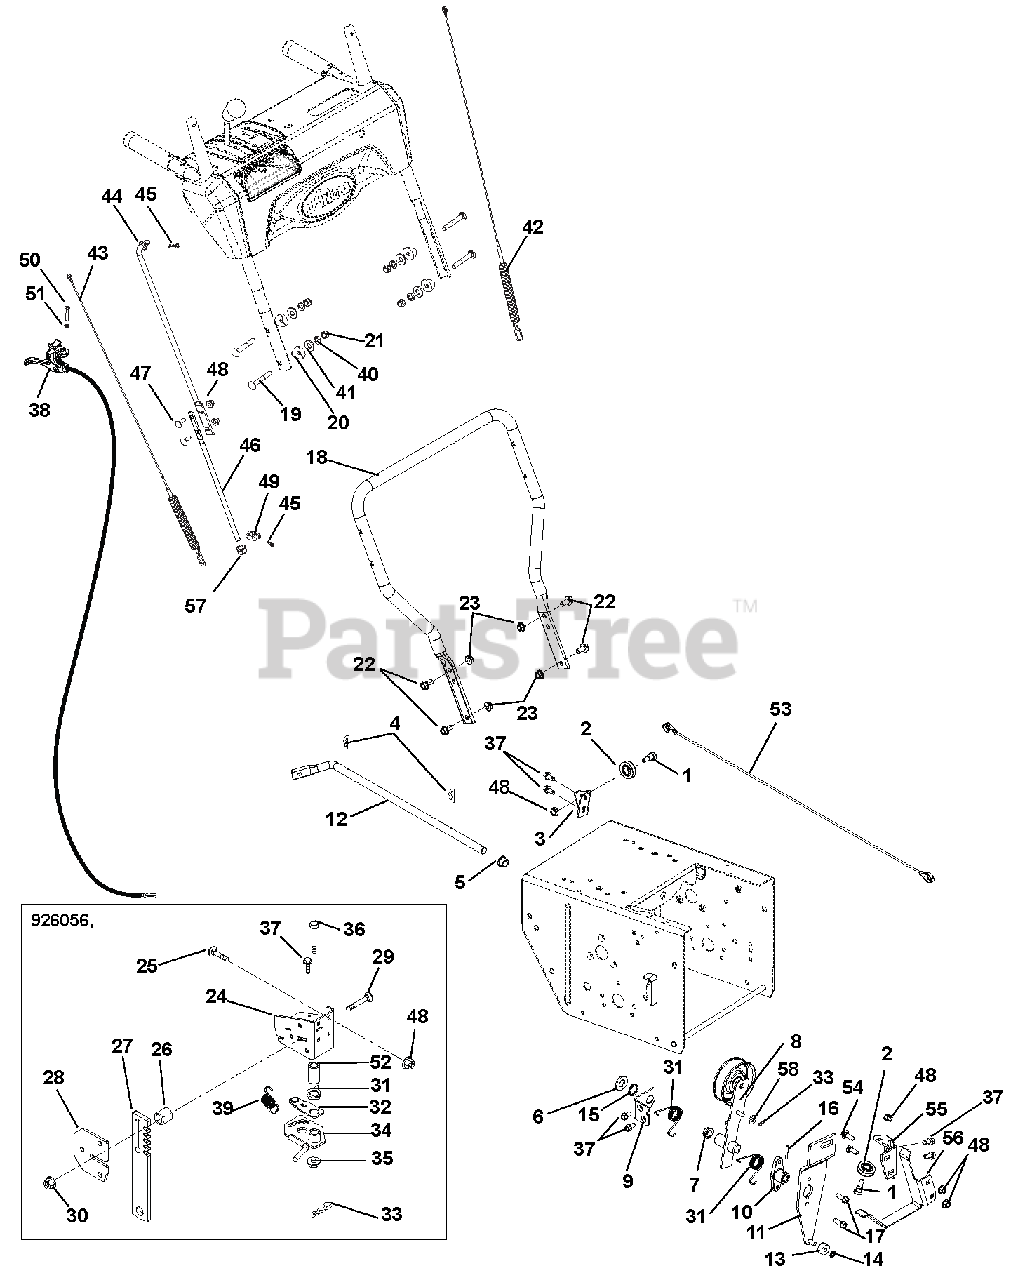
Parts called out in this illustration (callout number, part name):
1	BOLT, SHLDR-.375X.375X.25-20
2	PULLEY, CABLE
3	BRACKET, CABLE PULLEY
4	CLIP, SPRING
5	BUSHING, POLYLINER-.50 SPLIT
6	@WSHR-FL-STL.531X1.06X.095YWZC
7	BSHG,FLANGE .500X.625X.270X.75
8	ARM, TRACTION CLUTCH
9	BRACKET, SUPPORT
10	HUB, BRAKE ARM
11	ARM, IDLER-ATTACHMENT
12	ARM, ATTACHMENT
13	BSHG,SLV .265 X .625 X .375
14	RG-RTNG-EXT .250X.010
15	WAVE SPRING .600X.875X.25FH
16	PIN-ROLL .125X1.00
17	SCR-TAP .25-20X.75 HWH TR YWZ
18	HANDLEBAR, LOWER
19	@BLT-RDHDSQNK .31-18X2.25 G5YZ
20	SPACER, HANDLEBAR
21	@NUT-LK-NYL .312-18 YWZC
22	BLT-SERHFWH .38-16X.75 YWZC
23	@NUT-LK-TOP-FLG .38-16 YWZC
24	BRACKET, HEIGHT ADJUSTER-PRO
25	@BLT-RDHDSQNK .25-20X.75 G5YZ
26	SPACER .50 X .32 X .42
27	STOP, HEIGHT ADJUSTER-PRO
28	PLATE, HEIGHT ADJUSTER
29	@BLT-RHDSHSQNK.31-18X1.25 G5YZ
30	@NUT-LK-TOP-FLG .31-18 YWZC
31	SG-TORS .067X.88
32	ARM, OVERTRAVEL
33	PIN-HAIR INT .06X.18X.77
34	LOCK, HEIGHT ADJUSTER
35	NUT-LK-CTR-FLG .38-16 YWZC
36	@BLT-HEX .38-16X1.75 GR5 YWZC
37	SCR-TAP .25-20X.50 HWH TR YWZ
38	CABLE, TRACK REMOTE
39	SPRING-EXT .047 X .438 X 1.85
40	WSHR-LK .312X.097 HVY YWZC
41	@WSHR-FL-STL.38X.875X.083 YWZC
42	CABLE, UPPER TRACTION
43	CABLE, AUGER (DELUXE & PRO)
44	ROD, SHIFT - UPPER
45	PIN-HAIR INT .08X.18X1.18 YWZC
46	ROD. HYDRO SHIFT - LOWER
47	@BLT-RDHDSQNK .25-20X.75 G5YZ
48	@NUT-LK-TOP-FLG .25-20 YWZC
49	PIVOT,SHIFT ROD .375-16(TRUNN)
50	SCR-MCH .25-20X1.50 OVAL HD
51	WSHR-LK-INT .250 TH TYA
52	BSHG-SLV .385X.500X1.045
53	CABLE, TRACTION, HYDRO PRO
54	@BLT-RDHDSQNK .25-20X.75 G5YZ
55	BRACKET, CLUTCH CABLE
56	FINGER, BELT - FLAT
57	NUT-HEX-JAM .375-16 YWZC
58	@WSHR-FL-STL.281X.62X.065 YWZC
